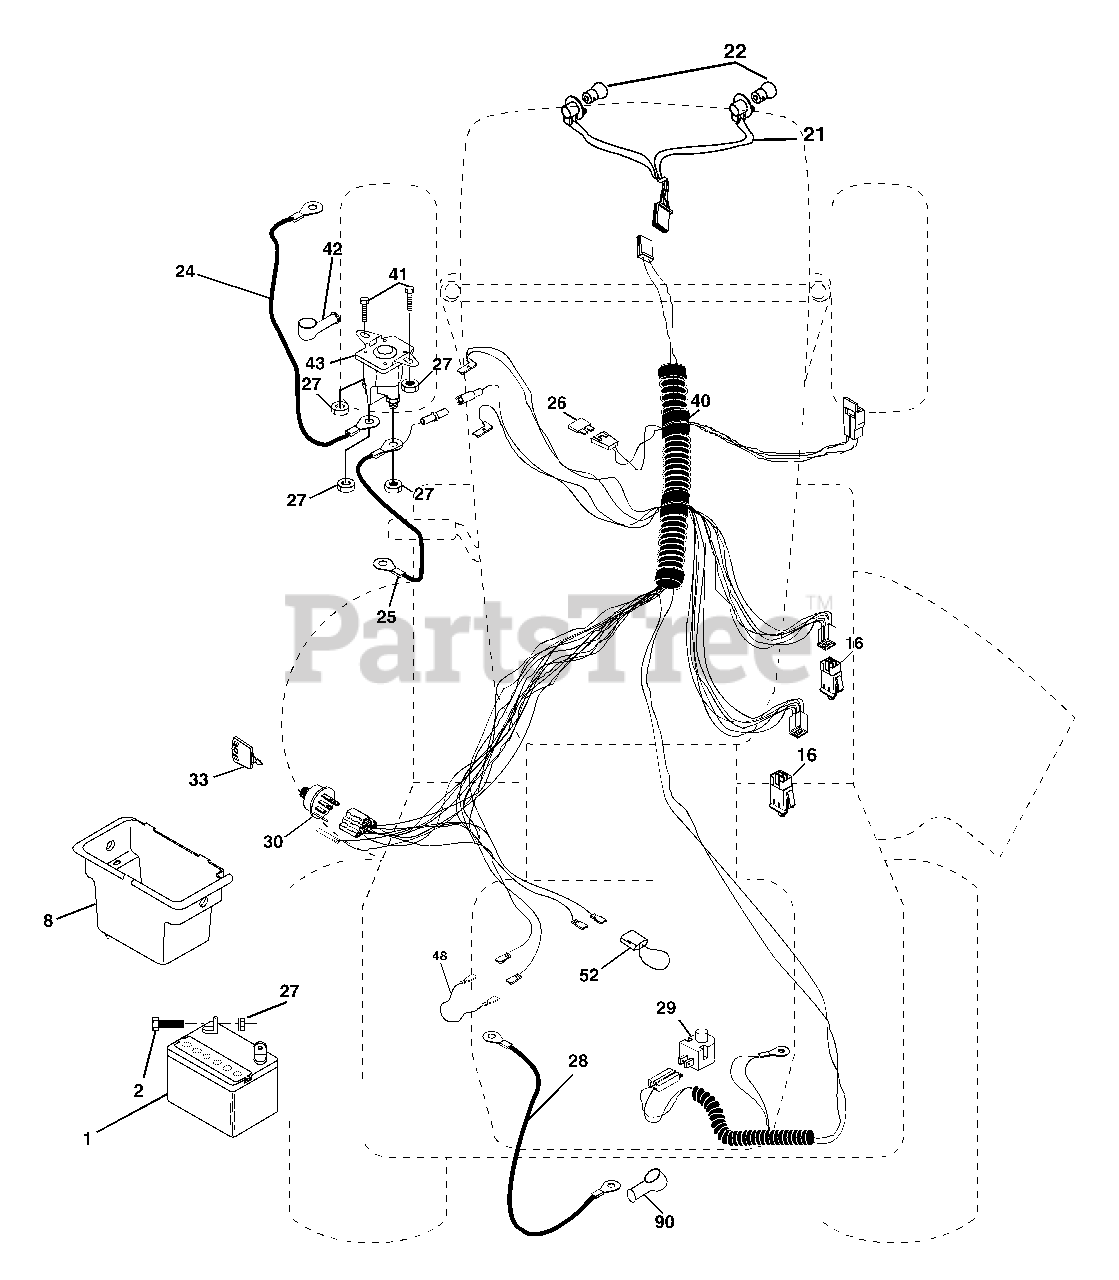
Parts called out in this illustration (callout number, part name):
1	Battery
2	Bolt Hex Hd 1/4-20unc X 3/4
8	Box Battery
16	Switch Interlock Push -In
21	Harness Asm Light W/4152J
22	Bulb Light #1156
24	Cable Battery 6 Ga 11"red
25	Cable Battery 6 Ga w/16 wire,red
26	Fuse 20 AMP
27	Nut Keps Hex 1/4-20 unc
28	Cable Ground 6 Ga 12" black
29	Switch Plunger Nc Gray
30	Switch Ign
33	Key Ign
40	Harness Ign
41	Bolt Blk Fin Hex 1/4-20 X 1/2
42	Cover Terminal Red
43	Solenoid
48	Adapter Ammeter
52	Protection Wire Loop
90	Cover Terminal
